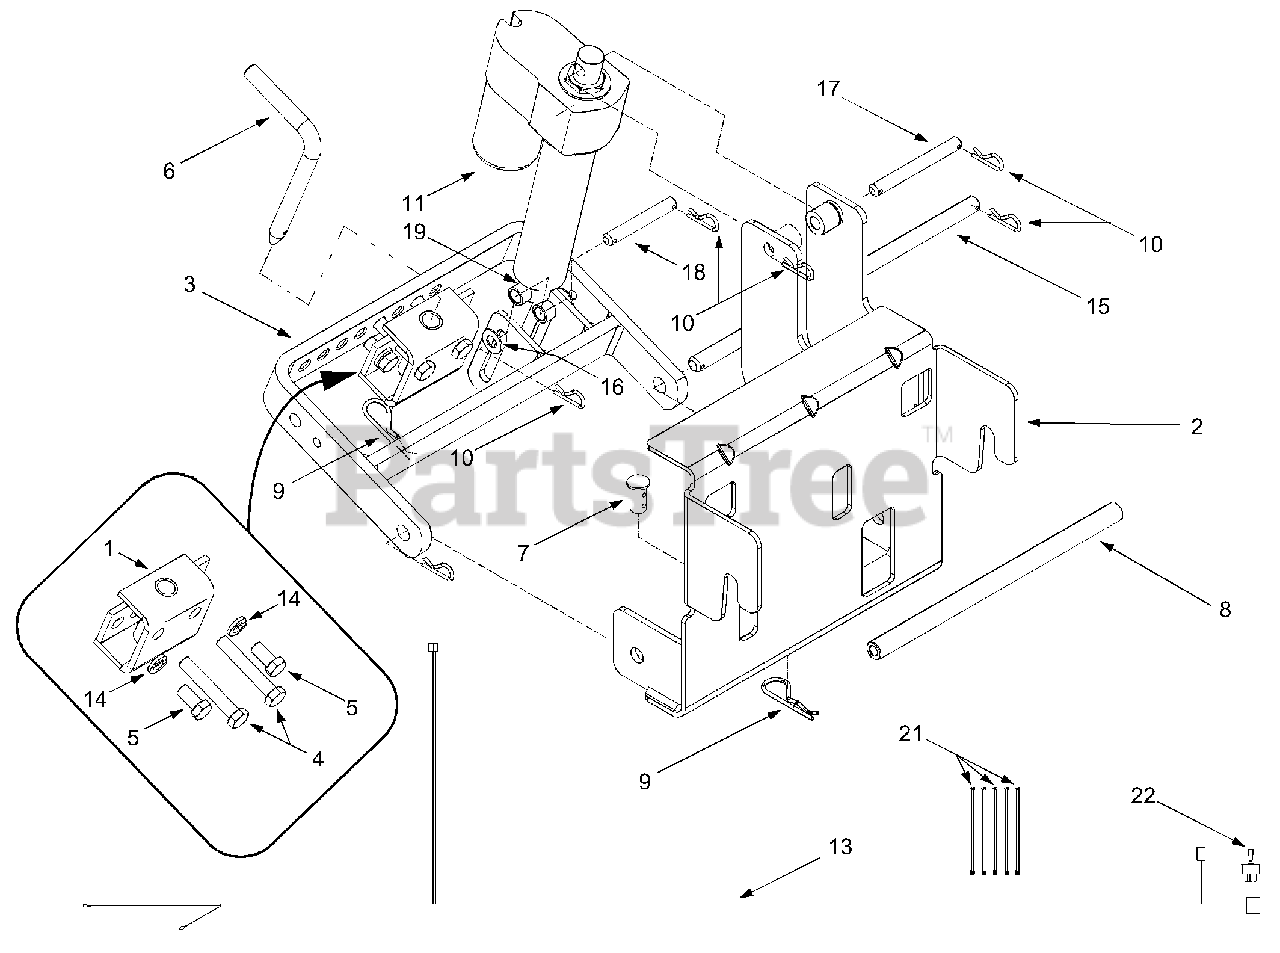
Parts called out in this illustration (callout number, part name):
5	Hex Cap Screw, 1/2-13 x 1 (Grade 5)
8	Support Rod, 3/4 x 13"
9	Internal Cotter Pin, .148 x 3
10	Internal Cotter Pin
11	Electromechanical Linear Actuator
13	Wire Harness
14	Lock Washer, 1/2
16	Flat Washer, .51 x 1.12 x .060
17	Upper Cylinder Support Rod
18	Lower Cylinder Support Rod
19	Spacer, .542 x .750 x .5
22	Toggle Switch
